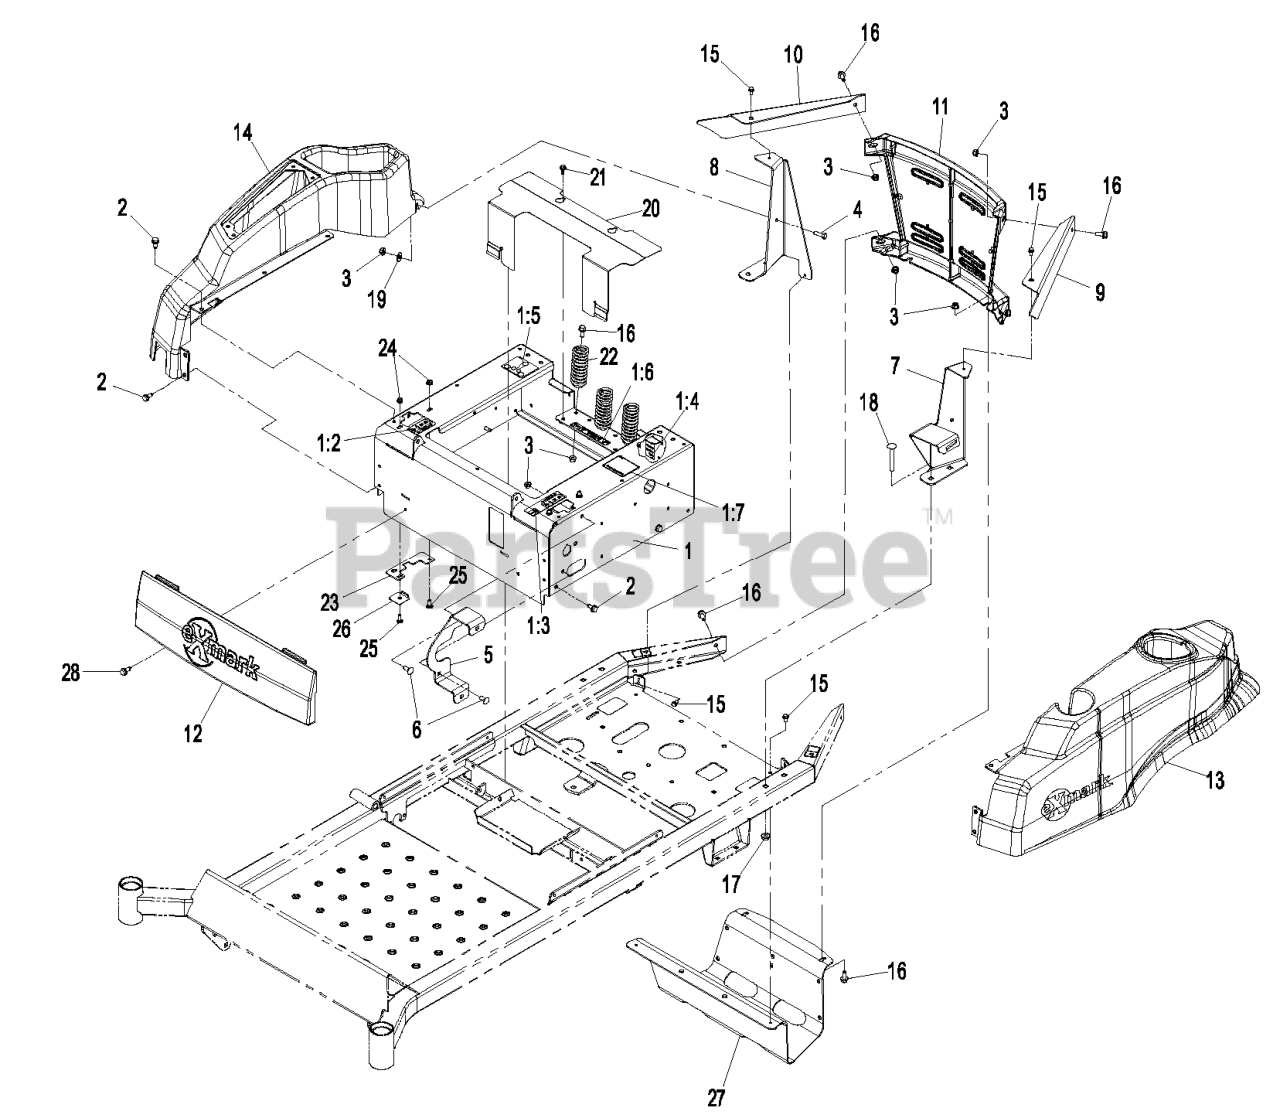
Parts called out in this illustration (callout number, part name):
1	ASM,SEAT BOX W/DECALS
1:2	DECAL-MOTION CONTROL
1:3	DECAL-CONTROL BRAKE
1:4	DECAL-FUSE BLOCK
1:5	DECAL-ROUTING, BELT
1:6	DECAL-DANGER
1:7	DECAL,ENGINE RPM
2	Screw-HWH 5/16-18 X 3/4 Tf
3	NUT-HF, NI
4	SCREW-HH
5	BRACKET-TANK MOUNT
6	SCREW-CARR
7	BRACKET,REAR TANK LH
9	GUARD,ENGINE LH
10	GUARD,ENGINE RH
11	CASTING,REAR EXMARK
12	PANEL,FRONT EXMARK
13	FENDER,EXMARK LH
14	FENDER,EXMARK RH
15	SCREW-HWH
16	SCREW-HHF
17	NUT-HF, NI
18	SCREW-CARR
19	WASHER-FLAT
20	COVER-HYDRO FAN
21	SCREW-HHF
22	SPRING-COMPRESSION
23	PLATE,NEUTRAL
25	BOLT-CARR
26	PLATE,TRACKING
27	GUARD-MUFFLER
